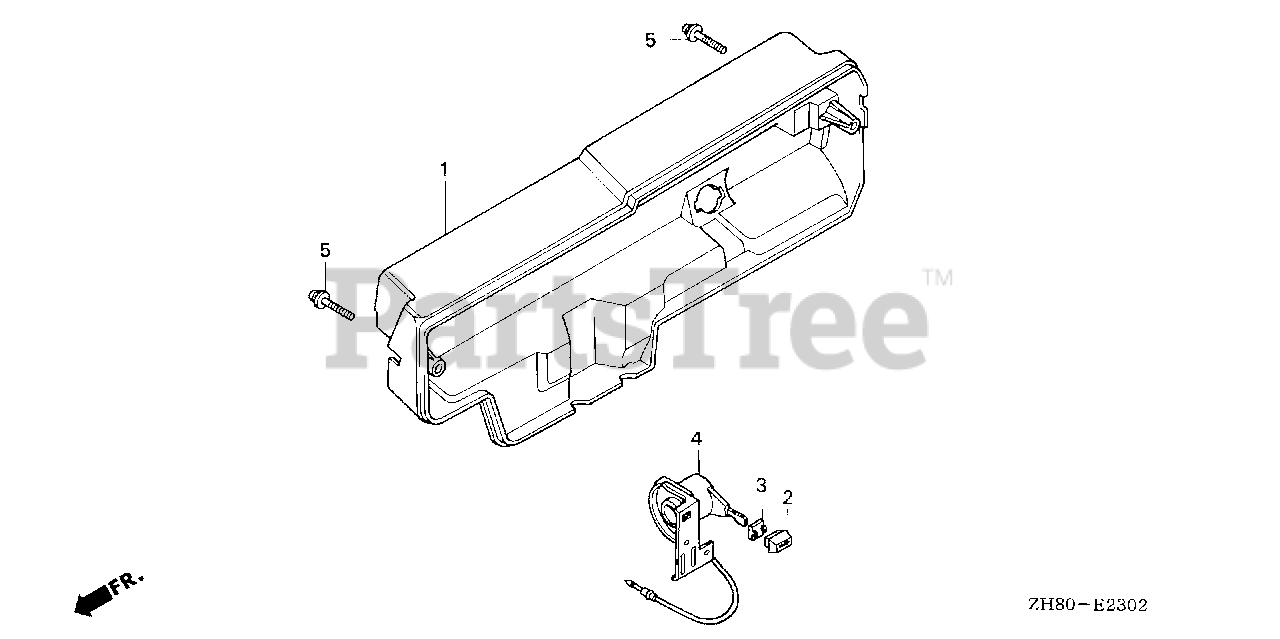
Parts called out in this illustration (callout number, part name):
1	CASE, CONTROL *R280* (POWER RED)
2	KNOB, PETCOCK LEVER
3	BUSH, CONTROL KNOB
4	SWITCH ASSY., ENGINE
5	SCREW-WASHER (6X40)
